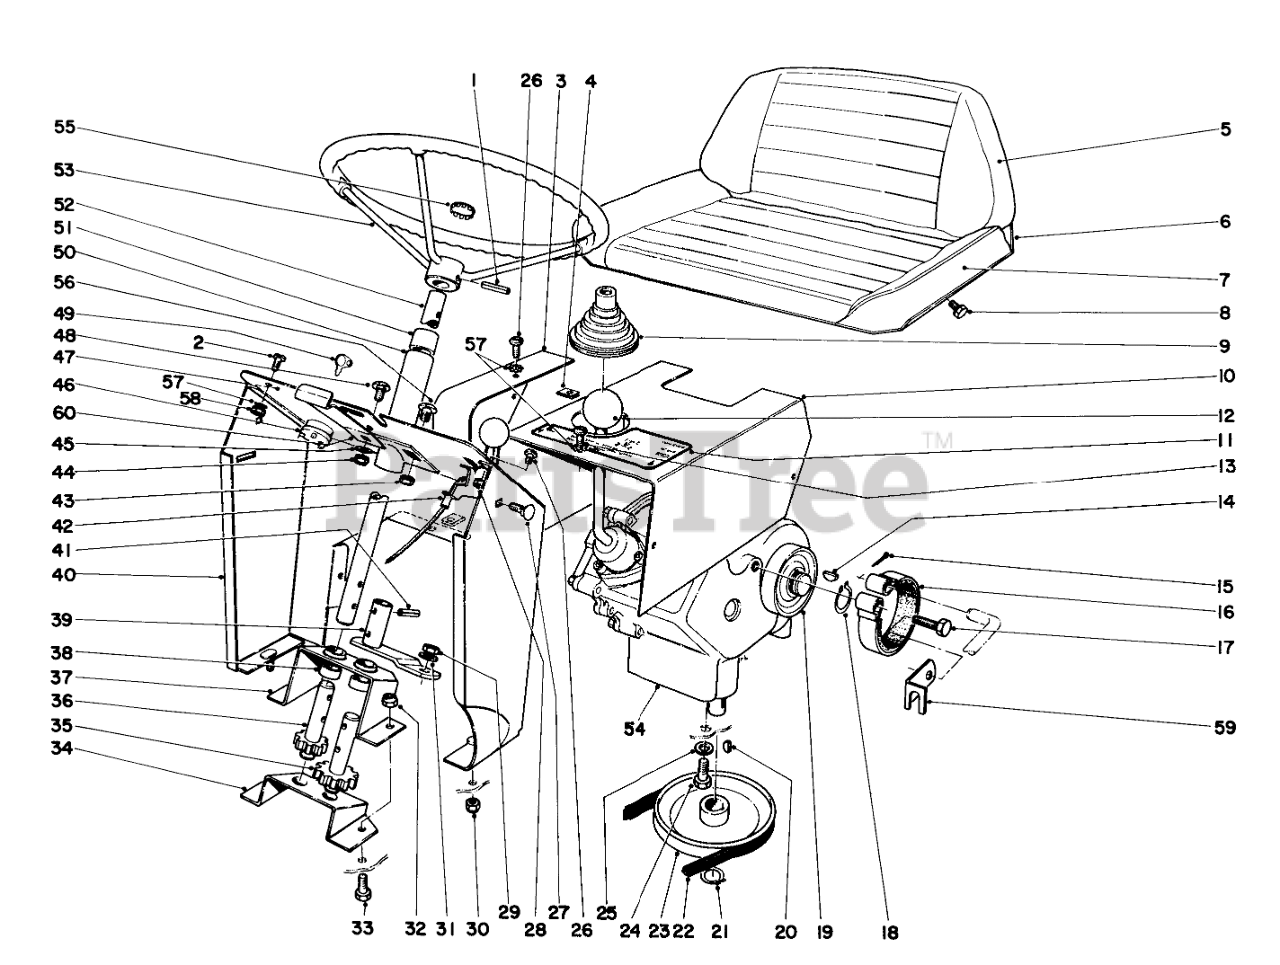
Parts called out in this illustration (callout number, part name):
1	PIN-ROLL
3	Chain Guard
4	NUT-CLIP,U
5	Cushion Back
6	Frame Seat
7	Cushion Seat
8	Screw
9	Boot Shift Lever
10	Cover Transmission
11	Decal Shift Pattern
13	10-24 X 3/8 PAN HD SC
14	KEY-WOODRUFF
15	PIN-COTTER
16	Brake Band
17	He Ha. Screw
18	Ring-Snap
19	Brake Drum
20	KEY-WOODRUFF
21	Retaining Ring
22	TRANS TO ENGINE BELT
23	PULLEY
24	Capscrew
25	WASHER-LOCK/SP
27	SCREW-CARR
28	NUT-KEPS
29	NUT-HEX
31	WASHER-LOCK
32	Nut
33	SCREW-HH
34	Bracket Steering
35	Steering Gear
36	Pinion Gear
37	Support Steering
38	Spacer
39	Steering Arm
40	Rear Hood Support (Recoil)
41	PIN-ROLL, SLOTTED
42	Throttle Control
43	Nut
44	NUT-LOCK, CONE
45	WASHER-FLAT
46	STARTER SWITCH
47	Decal Control Panel (Recoil)
48	Carriage Bolt
49	Key
50	Steering Tube Assy.
51	BUSHING
52	Shaft Steering
53	Steering Wheel
54	Transmission
56	Truss Head Screw
57	WASHER-LOCK, EXT
58	NUT-KEPS
59	Retainer Brake Rod
60	Hood Latch
